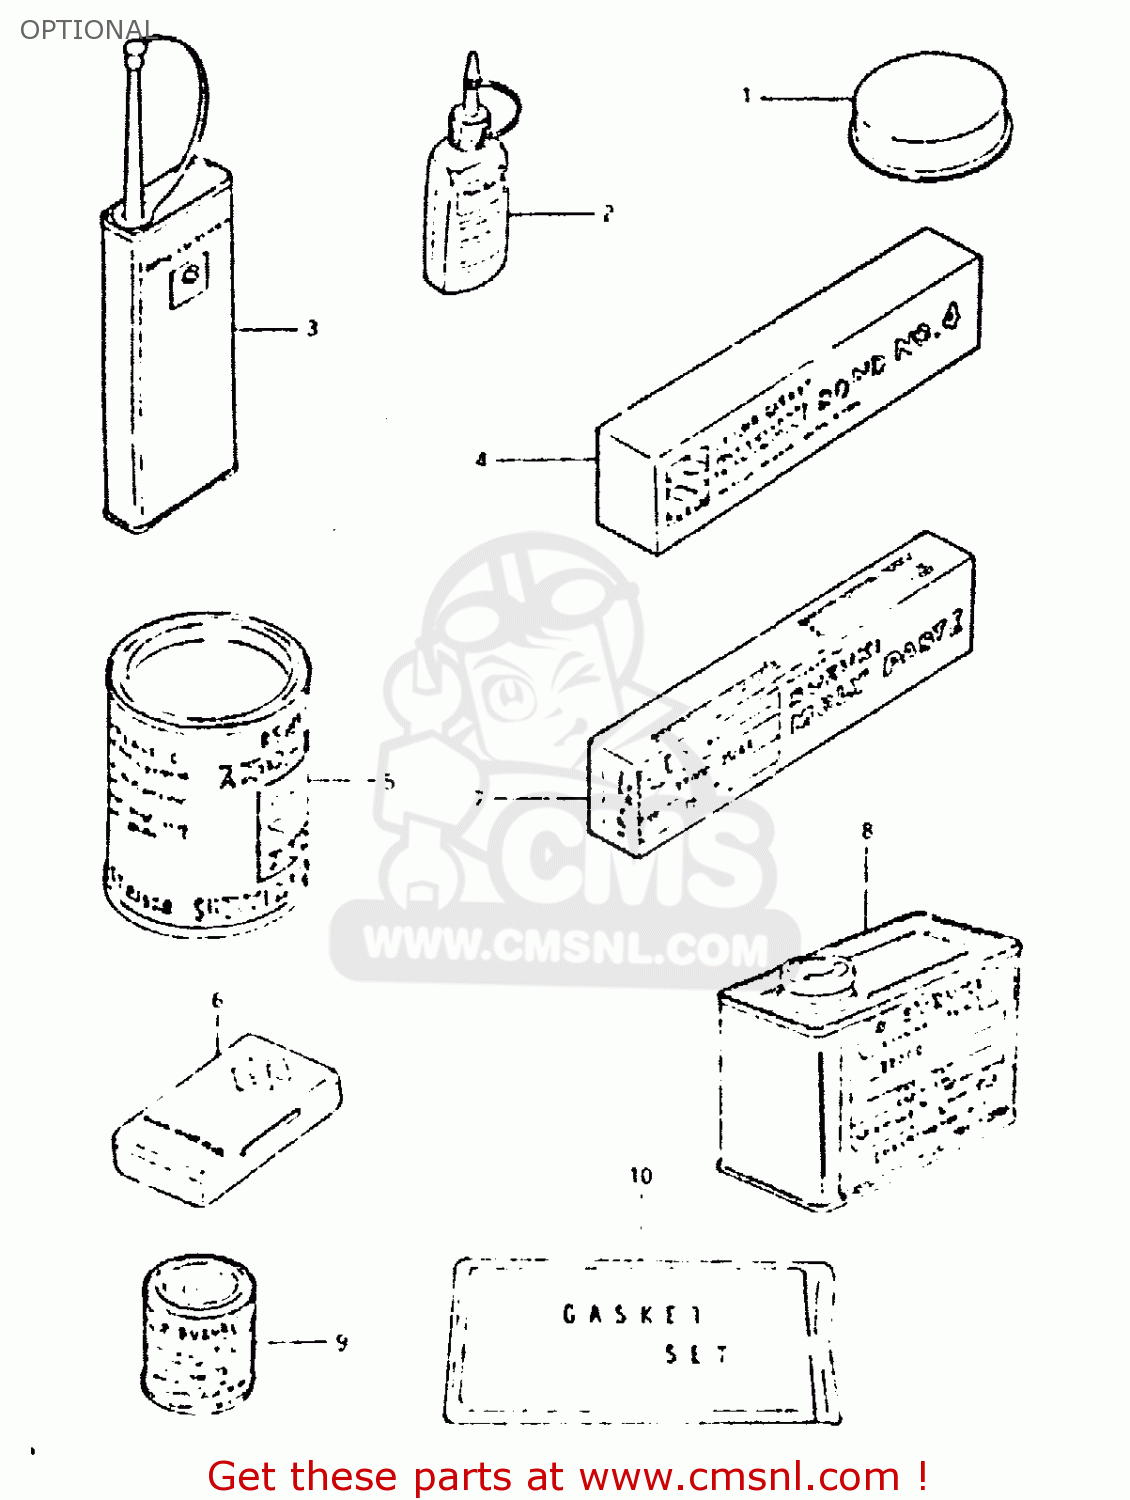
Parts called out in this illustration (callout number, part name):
1	GREASE,PBC FOR BRK PAD 20G
2	THREAD LOCK SUPER (1332B)
3	THREAD LOCK NO.1401 CLEAR 200G
4	BOND 1104
5	GREASE(C)EP2 LITHIUM 150G
6	TUBE REPARING TOOL
7	SUZUKI MOLY PASTE
8	PAINT (BLACK)
9	PAINT,BLACK
10	GASKET SET
